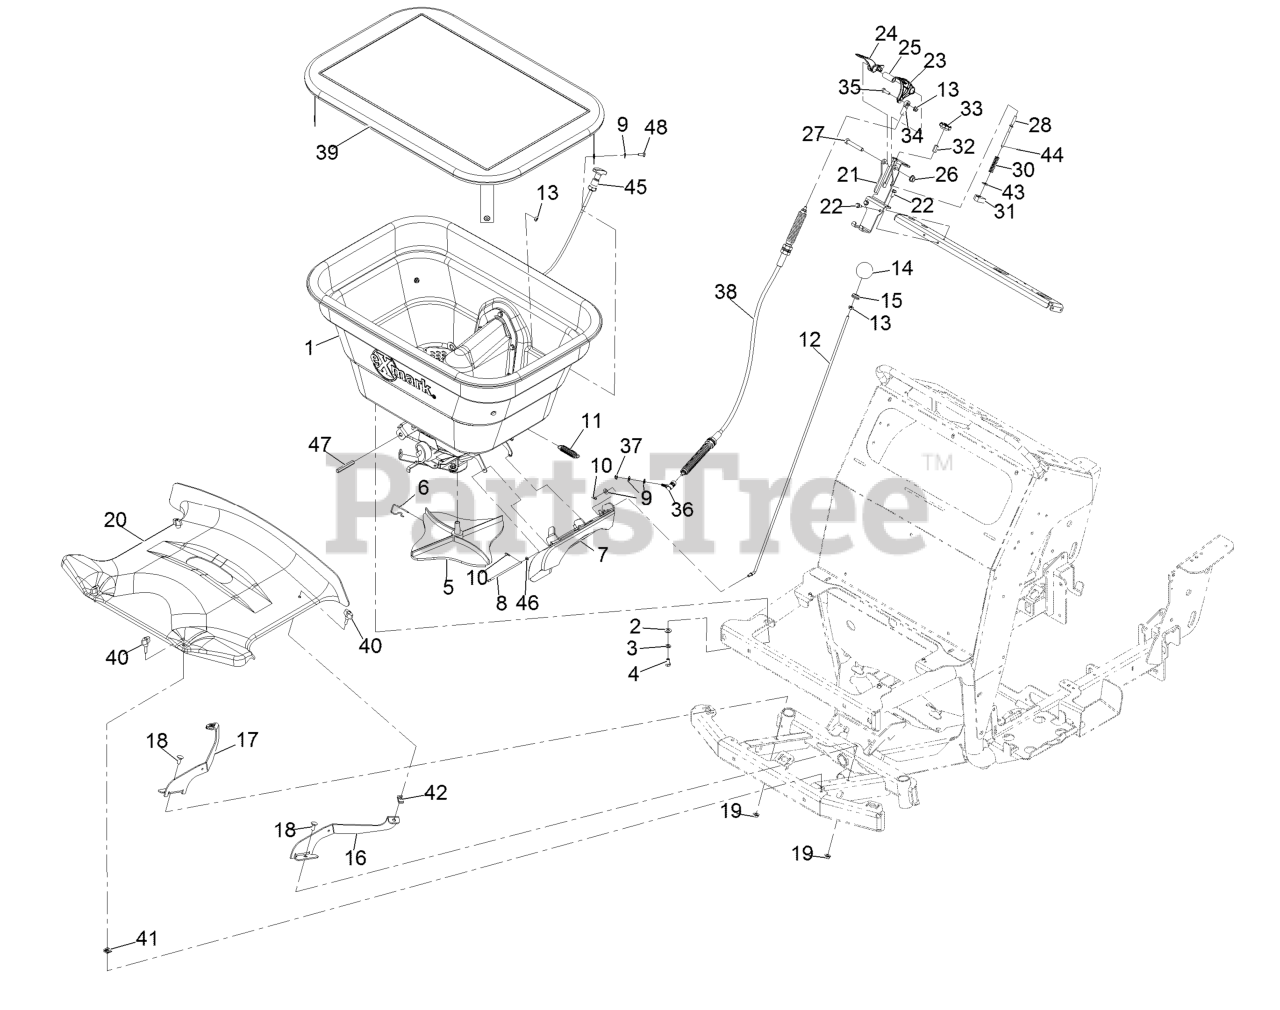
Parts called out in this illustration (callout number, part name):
1	Spreader Hopper ASM
3	Washer-Lock
4	Screw-HH
5	Spinner-Spreader
6	Clip-Spinner
7	Side Deflector ASM
8	Pin-Deflector SS
9	Washer-Flat
10	Pin-Cotter, Hair
11	Spring-Extension
12	Rod-Control, Deflector
13	Nut-Hex Flg
14	Knob-Rate, Flow
15	Grommet
16	Bracket-Cover, Front (LH)
17	Bracket-Cover, Front (RH)
18	Screw-CARR
19	Nut-Hex Flg
20	Cover-Front, Spreader/Sprayer
21	Mount-Handle
22	Screw-HWH 1/4-20 X .62
23	Lever-Spread, Wide
24	Lever-Spread, Narrow
26	Nut-Hex Flg
27	Screw-HH 3/8-16 X 2 1/4
28	Link-Adjust, Narrow
30	Spring-Compression, Bail
31	Stop-Spread, Narrow
32	Nut-Coupler
34	Rod End-Ball Joint
35	Screw-HH 1/4-20 X 7/8 SS
36	Ball-Joint
37	Nut-Hex, NI
39	Cover-Hopper
41	Nut-Retainer, U Style
42	Nut-Retainer, U Style
44	Pin-Cotter 3/32 X 1/2
45	Cable-Control, Turn Lock
46	Washer-Flat
47	Post-Hex, Diffuser Guide
48	Screw-HH 1/4-20 X 5/8 SS
